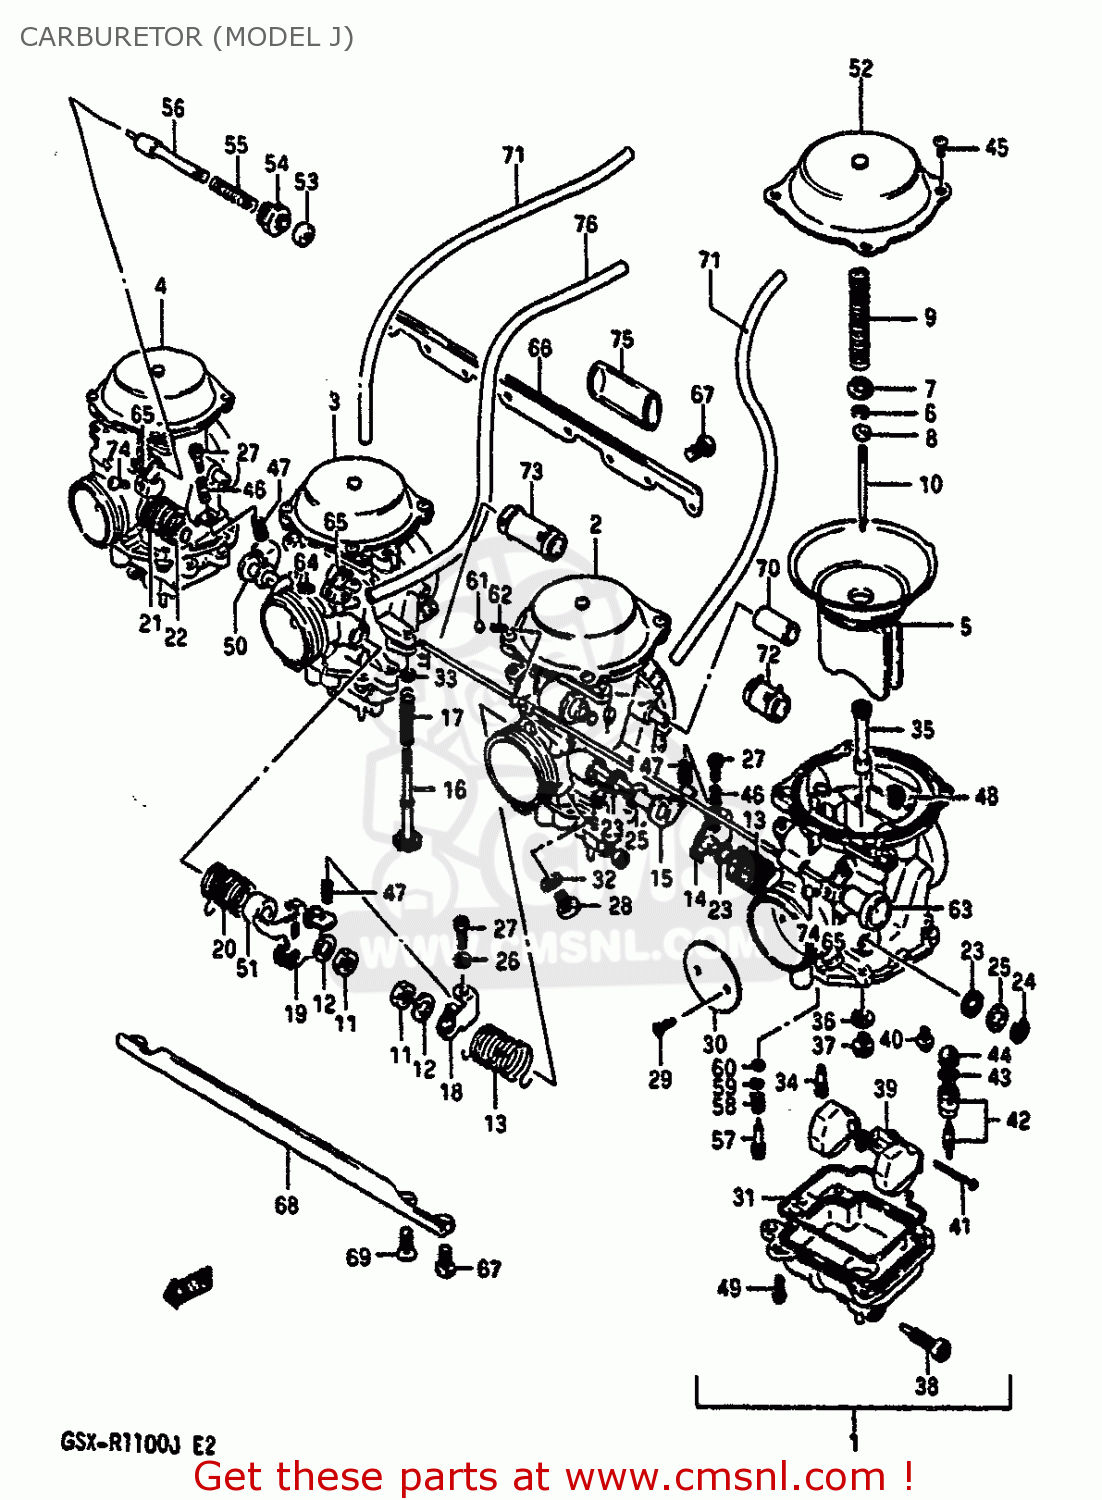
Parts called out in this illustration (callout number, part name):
1	CARBURETOR ASSY,LH
2	CARBURETOR ASSY,ML
3	CARBURETOR ASSY,MR
4	CARBURETOR ASSY,RH
5	DIAPHRAGM ASSY
6	CLIP
7	RING
8	RING
9	SPRING
10	NEEDLE,JET
11	NUT
12	WASHER
13	SPRING
14	SHAFT ASSEMBLY
15	SHAFT ASSEMBLY
16	ADJUSTER
17	SPRING
18	LEVER
19	LEVER ASSEMBLY
20	SPRING
21	SPRING
22	SHAFT ASSEMBLY
23	SEAL
24	E RING
25	GASKET,THROTTLE SHAFT (NAS)
26	NUT,THROTTLE ROD
27	SCREW
28	SCREW
29	SCREW
30	VALVE,THROTTLE (130)
31	O RING,FLOAT CHAMBER
32	WASHER
33	WASHER
34	JET,PILOT(42.5)
35	JET,NEEDLE (O-9)
36	WASHER,NEEDLE NOZZLE
37	JET,MAIN(130)
38	SCREW
39	FLOAT
40	SCREW
41	PIN,FLOAT
42	VALVE ASSY,NEEDLE
43	O-RING,NEEDLE VALVE
44	FILTER
45	SCREW
46	SPRING
47	SPRING,THROTTLE SCREW
48	JET,AIR(150)
49	SCREW
50	SHAFT ASSEMBLY
51	RING
52	COVER,DIAPHRAGM
53	CAP,STARTER VALVE
54	GUIDE SCREW,PLUNGER
55	SPRING
56	PLUNGER ASSY
57	SCREW,PILOT
58	SPRING
59	WASHER
60	O RING,PILOT AIR SCREW
61	BALL,CARBURETOR
62	SPRING
63	SHAFT ASSEMBLY
64	SCREW
65	LEVER
66	PLATE
67	SCREW
68	PLATE
69	SCREW
70	HOSE,CARBURETOR
71	HOSE
72	HOSE SET (3X5X18)
73	HOSE ASSY
74	SCREW
75	HOSE
76	HOSE
